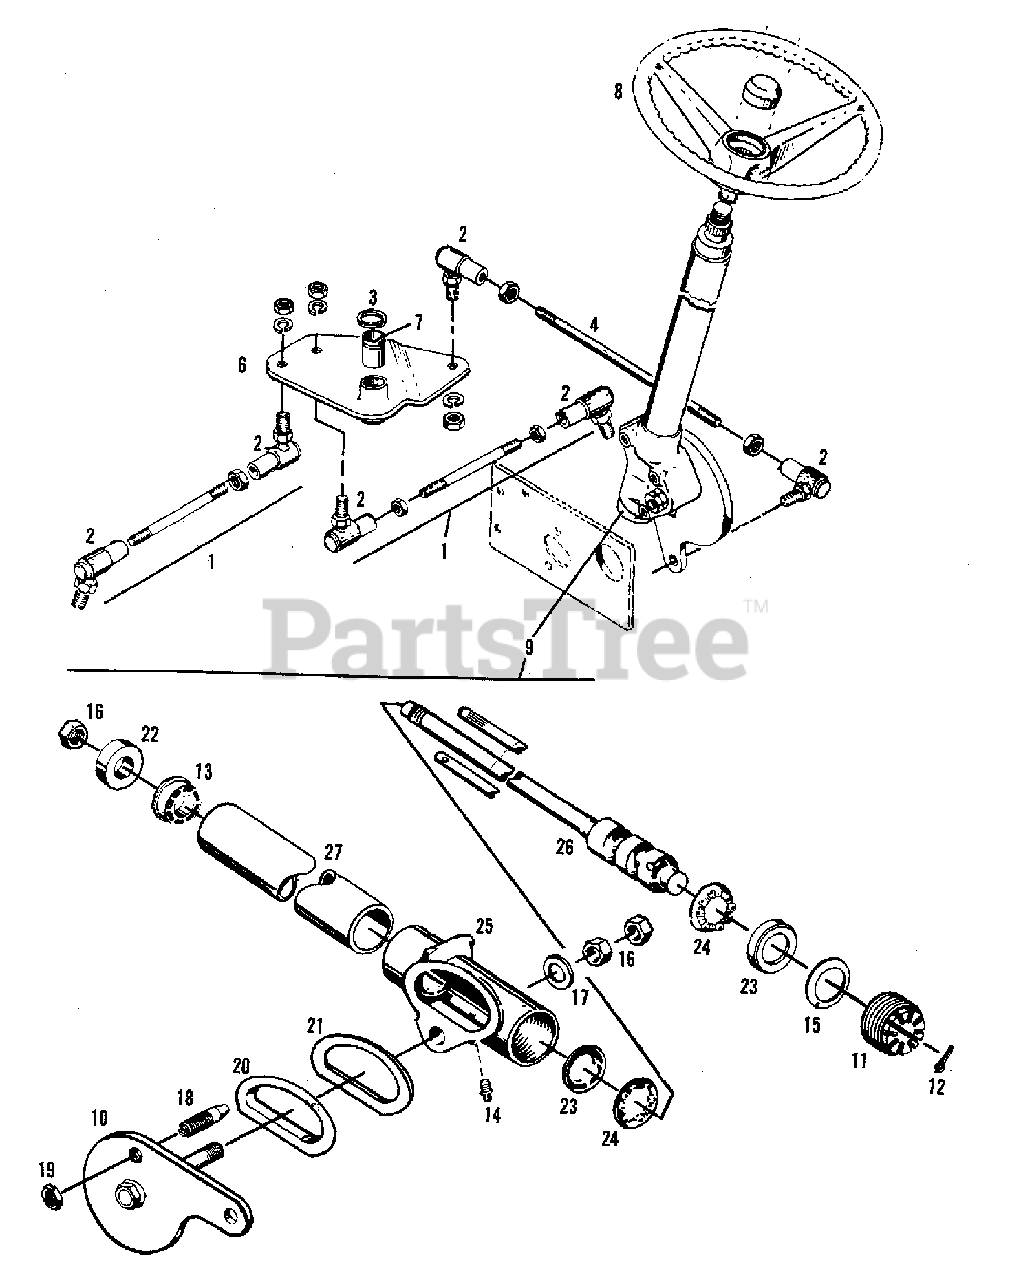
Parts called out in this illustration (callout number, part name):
1	LINK ASSEMBLY, L.H. (Includes BALL JOINTS & NUTS)
1	LINK ASSEMBLY, R.H. (Includes BALL JOINTS & NUTS)
1	NUT, 1/4NF, Jam Lock
1	NUT, 1/2NF, Centerlock
2	LOCKWASHER, 1/2
2	NUT, 1/2NF
2	NUT, 1/2NF, Jam Lock
3	RING, External Retaining
3	WASHER, 1.015 x 1-5/8 x 12 Ga
4	ROD, Drag
5	GREAR BOX, Steering
5	CAPSCREW, 3/8NC x 1
5	LOCKWASHER, 3/8
5	CAPSCREW, 5/16NC x 1-1/4 (See NOTE)
5	NUT, 5/16NC (See NOTE)
6	BELLCRANK ASSEMBLY
7	BEARING, Sleeve
7	WHEEL, Steering (W/o Spline)
8	WHEEL, Steering (W/ Spline)(Bolted Type)
8	GEAR ASSEMBLY, Steering (Includes Items 10-27)
9	LEVER & BOLT ASSEMBLY
11	PLUG, Adjustment
12	PIN, Cotter, 1/8 x 1/2
14	FITTING, Grease
15	WASHER, Bellville
16	NUT, Jam, 5/8-18, Hexagon (1 Nut Used w/Spline Type)
19	NUT, Adjustment
20	RETAINER, Seal
22	SEAL, Dust
23	CUP, Ball (Includes Item 14)
24	BALL & RETAINER
25	HOUSING (Not Serviced)
26	CAM (Not Serviced)
27	TUBE, Jacket (Not Serviced)
